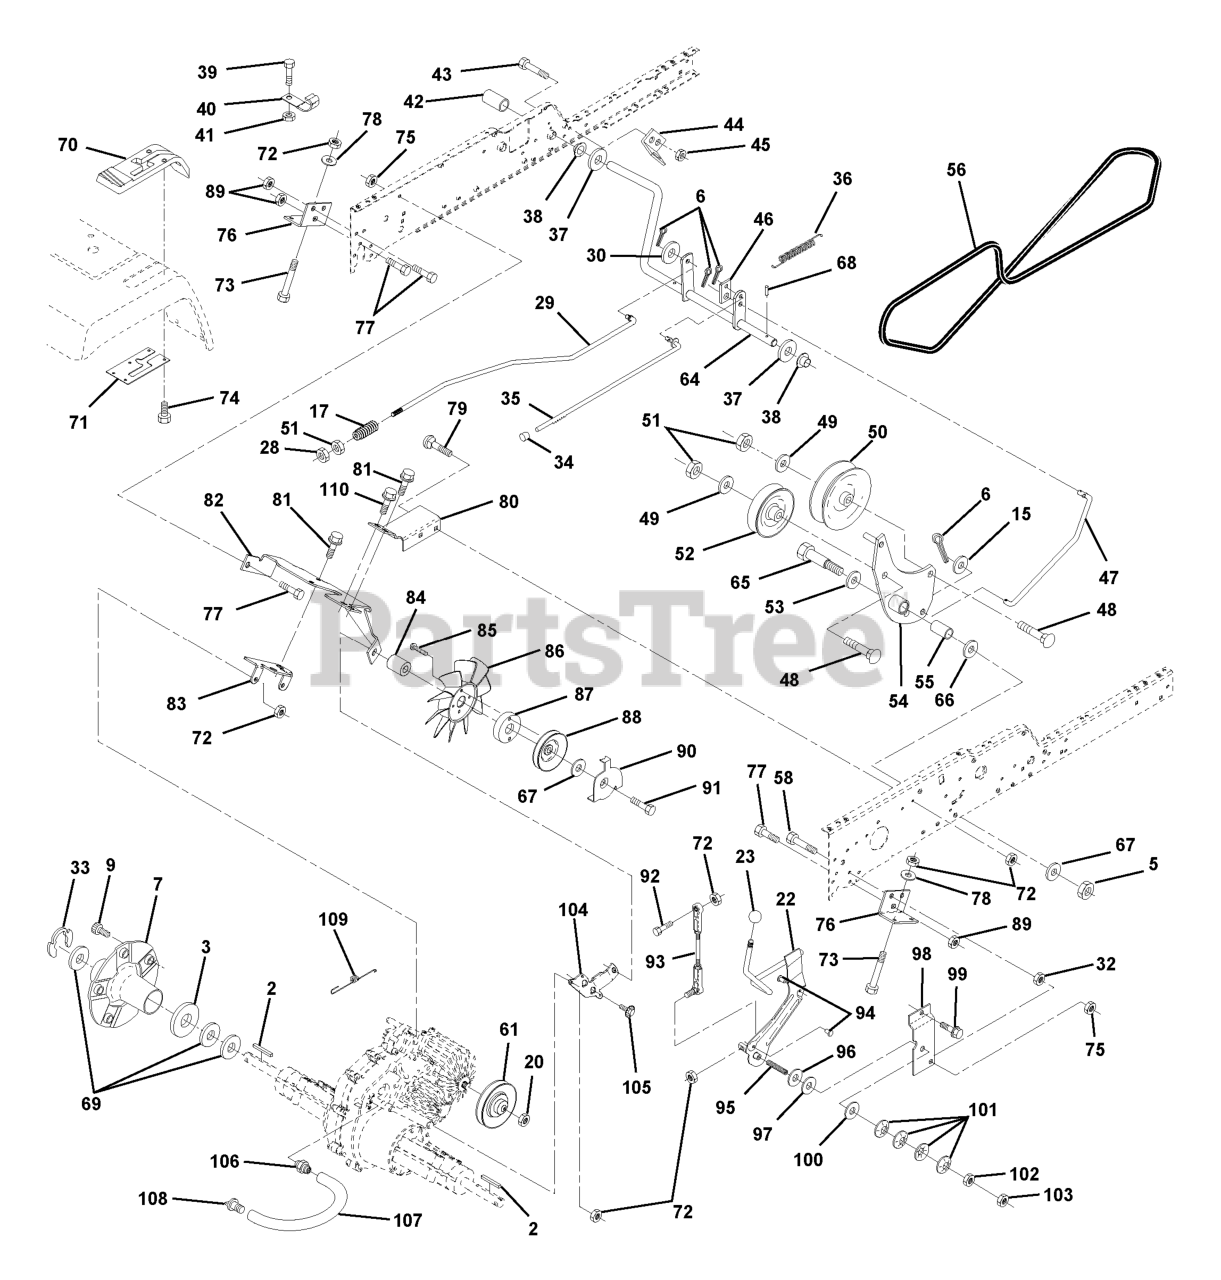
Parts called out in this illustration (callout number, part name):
2	KEY 1/4 X 2.5
6	COTTER PIN
7	HUB ASMBLY
9	HUB BOLT
15	WASHER
17	SPRING.ROD.BRAKE
20	NUT.HEX.1/2-20
22	SHAFT ARM ASMBLY
23	KNOB.DELUXE.(PISTOL.GRIP).BLAC
28	NUT
30	WASHER
33	E RING HYT
34	PLUNGER CAP
35	PARKING BRAKE ROD
36	SPRING DRIVE GROUND
39	Screw Fin #10-24 x 1
40	ACT-SWITCH T
41	LOCKNUT
42	COVER, PEDAL (1 2)
43	BOLT.HEX.1/4.X.3/4.DICHROMATE
44	BRKT SWITCH GT
45	LOCKNUT.NYLOC.1/4-20
46	RETAINER SPRING
47	CLUTCH ROD
49	Washer 13/32 x 7/8 x 13 Ga
50	FLAT IDLER PULLEY
51	NUT
52	PULLEY.IDLER.V.
54	CLUTCH ARM ASSY
55	BEARING LT (2 2)
58	BOLT.HEX.7/16-14.FINISHED
64	PEDAL SHAFT
66	WASHER.BLADE
67	WASHER
68	ROLL PIN STD
70	CONSOLE
71	PLATE SHIFT CONSOLE
72	NUT.71038.31-18.HEX.NYLOCK
73	Bolt Fin Hex 5/16-18 x 3
74	SCREW.HI-LO.CONSOLE
75	Nut Lock Hex 7/16
76	BRACKET TRANSAXLE
77	BOLT
79	BOLT.CARR.5/16-18X5/8.SHORT
80	TORQUE BRACKET RH
81	SCREW
82	BRACKET
83	STRAP TORQUE MID
85	Screw #10-24 x 1-1/4
86	FAN 7" HYDRO
87	ADAPTOR.FAN.TRANSAXLE.VGTH
88	IDLER PULLEY
89	Nut, Crownlock 7/16-14
90	KEEPER.BELT
91	SCREW.HXWSH.3/8
92	BOLT
93	LINK ASM SHIFT
94	FASTENER.XMAS.TREE
95	Screw Set 5/16-18 x 1.75
98	SHIFT BRACKET
99	SCREW LT
102	NUT
103	JAM NUT TI
104	BRACKET IDLER
105	SCREW CRT
106	VENT FITTING
108	VENT CAP 70109
109	RETURN SPRING
110	HINGE SCREW
